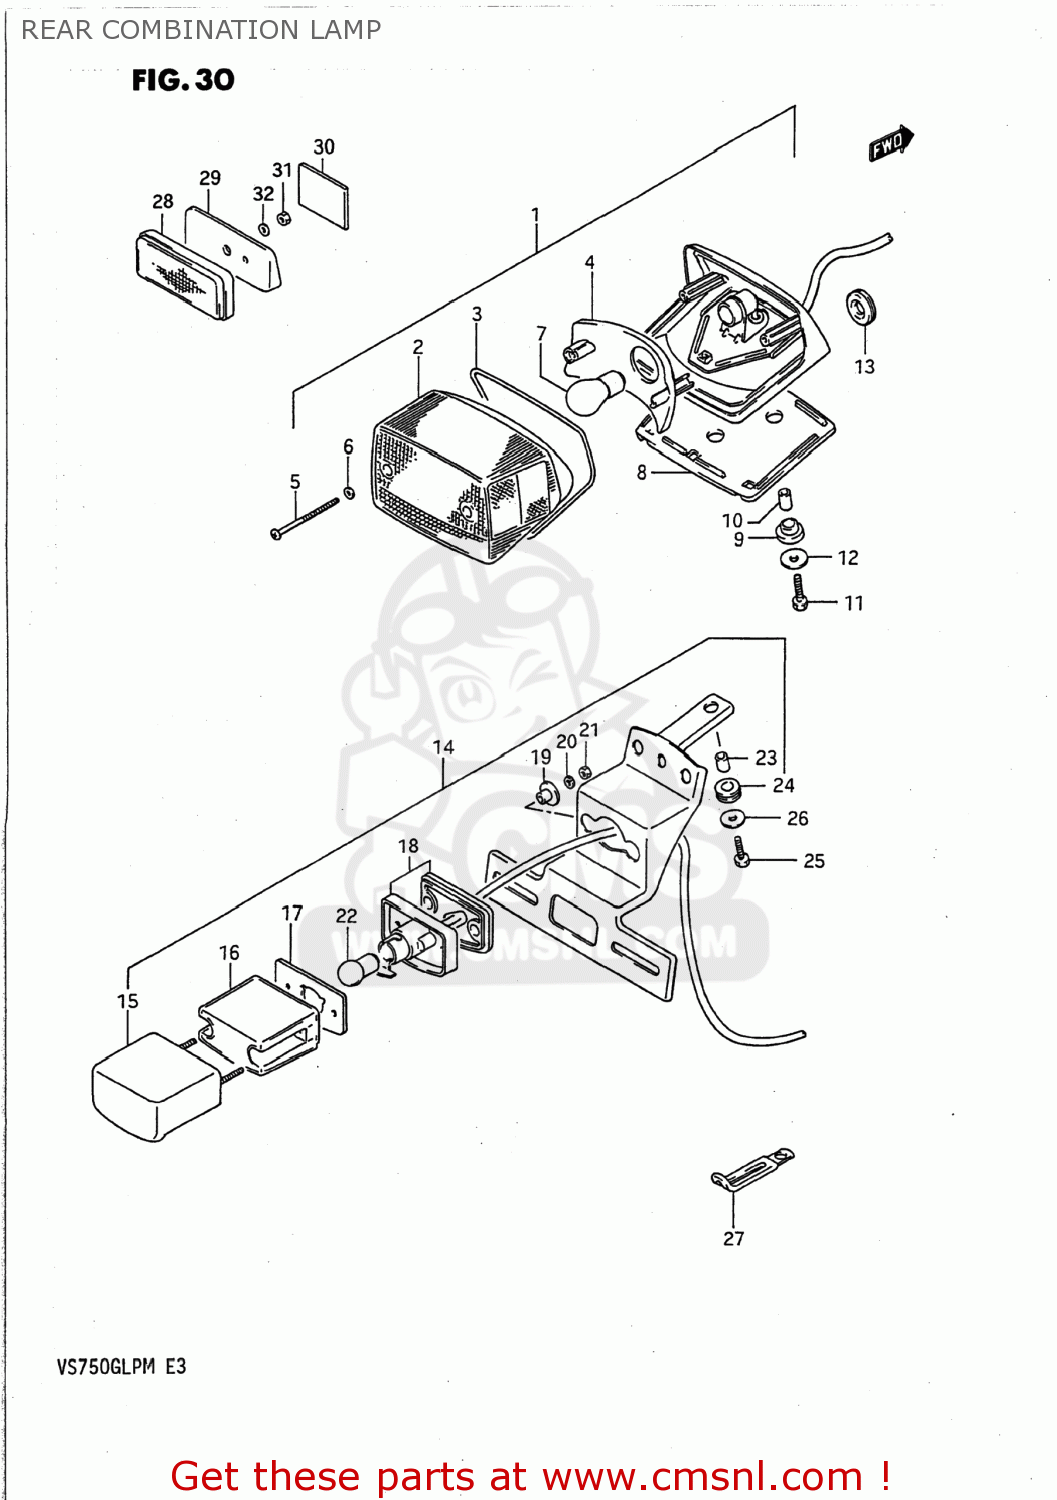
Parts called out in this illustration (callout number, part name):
1	LAMP ASSEMBLY,REAR COMBINATION
2	LENS
3	GASKET (NAS)
4	REFLECTOR
5	SCREW
6	GASKET (NAS)
7	BULB(12V21/5W,BF141-49642A)
8	CUSHION
9	CUSHION
10	SPACER
11	BOLT
12	WASHER
13	GROMMET
14	LAMP ASSY,LICENSE
15	COVER,LICENSE LAMP
16	LENS
17	GASKET,LICENSE LAMP (NAS)
18	HOUSING,LICENSE LAMP
19	SPACER
20	WASHER,LOCK 4M
21	NUT
22	BULB
23	SPACER
24	CUSHION
25	BOLT,M6X1X20
26	WASHER
27	CLAMP L:35
28	REFLEX REFLECTOR ASSY,RR
29	SPACER
30	COVER,HARNESS
31	NUT
32	WASHER
